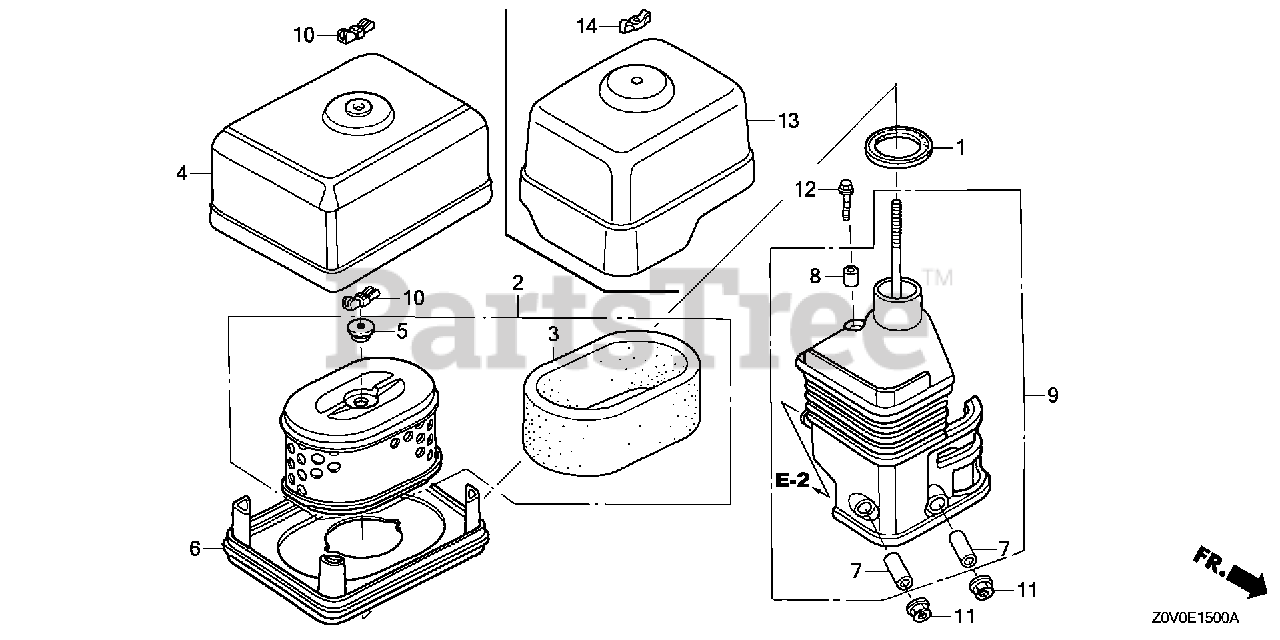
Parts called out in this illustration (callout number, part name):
1	GASKET, ELBOW
2	ELEMENT, AIR CLEANER (DUAL)
3	FILTER (OUTER)
4	COVER, AIR CLEANER (DUAL)
5	GROMMET, AIR CLEANER
7	COLLAR, AIR CLEANER
8	COLLAR B, AIR CLEANER
9	ELBOW, AIR CLEANER
10	NUT, TOOL BOX SETTING
11	NUT, FLANGE (6MM)
12	BOLT, FLANGE (6X20)
